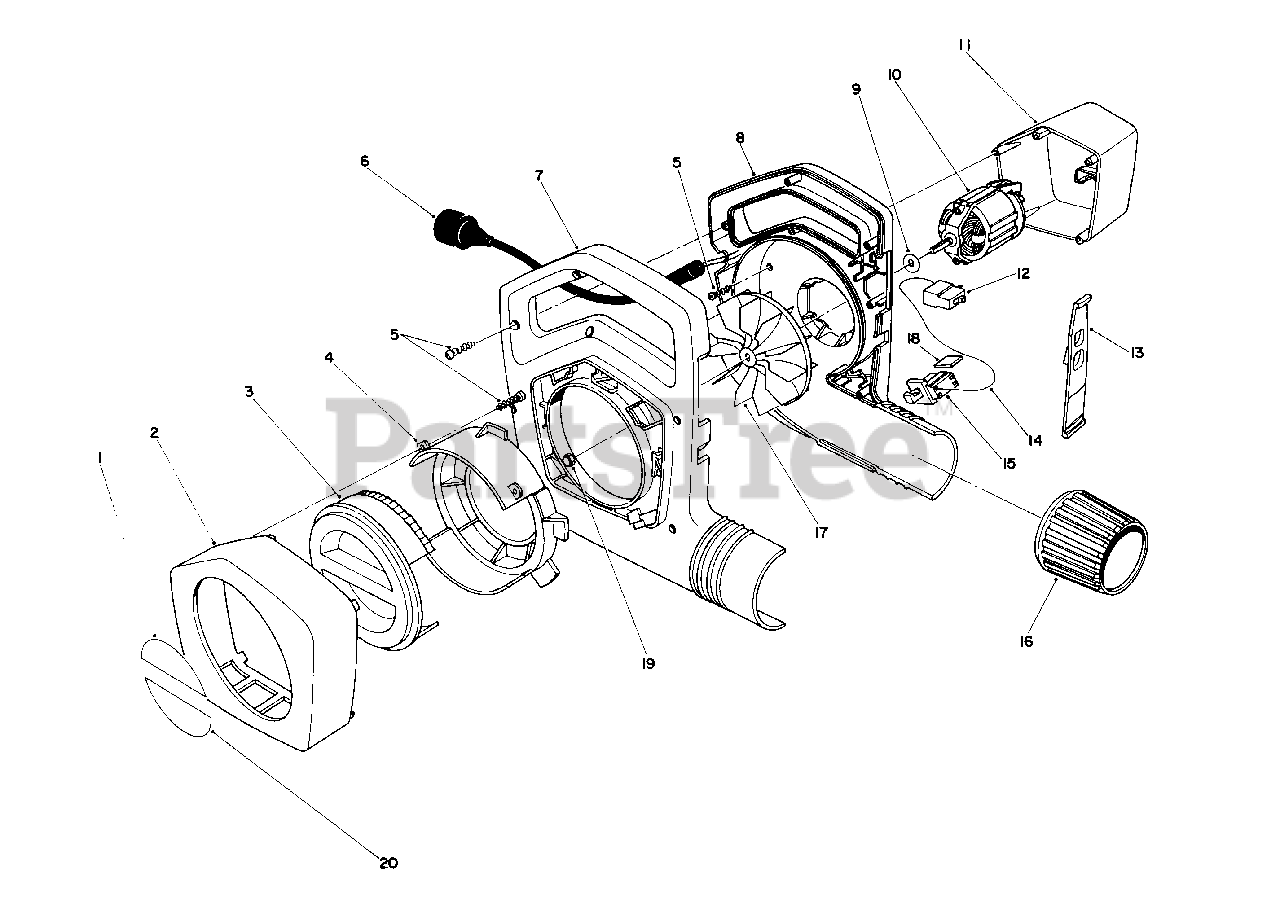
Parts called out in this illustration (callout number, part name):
1	Decal-Upper Choke (Model No. 51535)
1	Decal-Upper Choke (Model No.51545)
2	Ring-Trim
3	Adjuster-Choke
4	Ring-Tab
5	Screw
6	Cord-Power Supply
7	Housing Assembly-R.H.
8	Housing-L.H.
9	Washer-Impeller (Used on Model No. 51545-9000001 thru 9033219)
9	Washer-Impeller (Used on Model No. 51535-9000001 & up and Model 51545-9033220 & up)
10	Motor (Used on Model 51545-9000001 thru 9033219)
10	Motor (Used on Model 51535-9000001 & up and Model 51545-9033220 &up)
11	Cover Motor (Used on Model No. 51545-9000001 thru 903329)
11	Cover Motor (Used on Model No. 51535-9000001 & up and Model 51545-903322 & up)
12	Switch-On/Off (Model No. 51535)
12	Switch-Two Speed (Model 51545)
13	Cam-Switch-On/Off (Model 51535)
13	Cam-Switch-Two Speed (Model 51545)
14	Wire-Internal
15	Switch-Interlock
16	Collar-Output
17	Impeller (Used on Model 51545-9000001 thru 9033219)
17	Impeller (Used on Model 51535-9000001 & up and Model 51545-9033220 & up)
18	Plug-Dust
20	Decal-Lower Choke (Model 51535)
20	Decal-Lower Choke (Model 51545)
